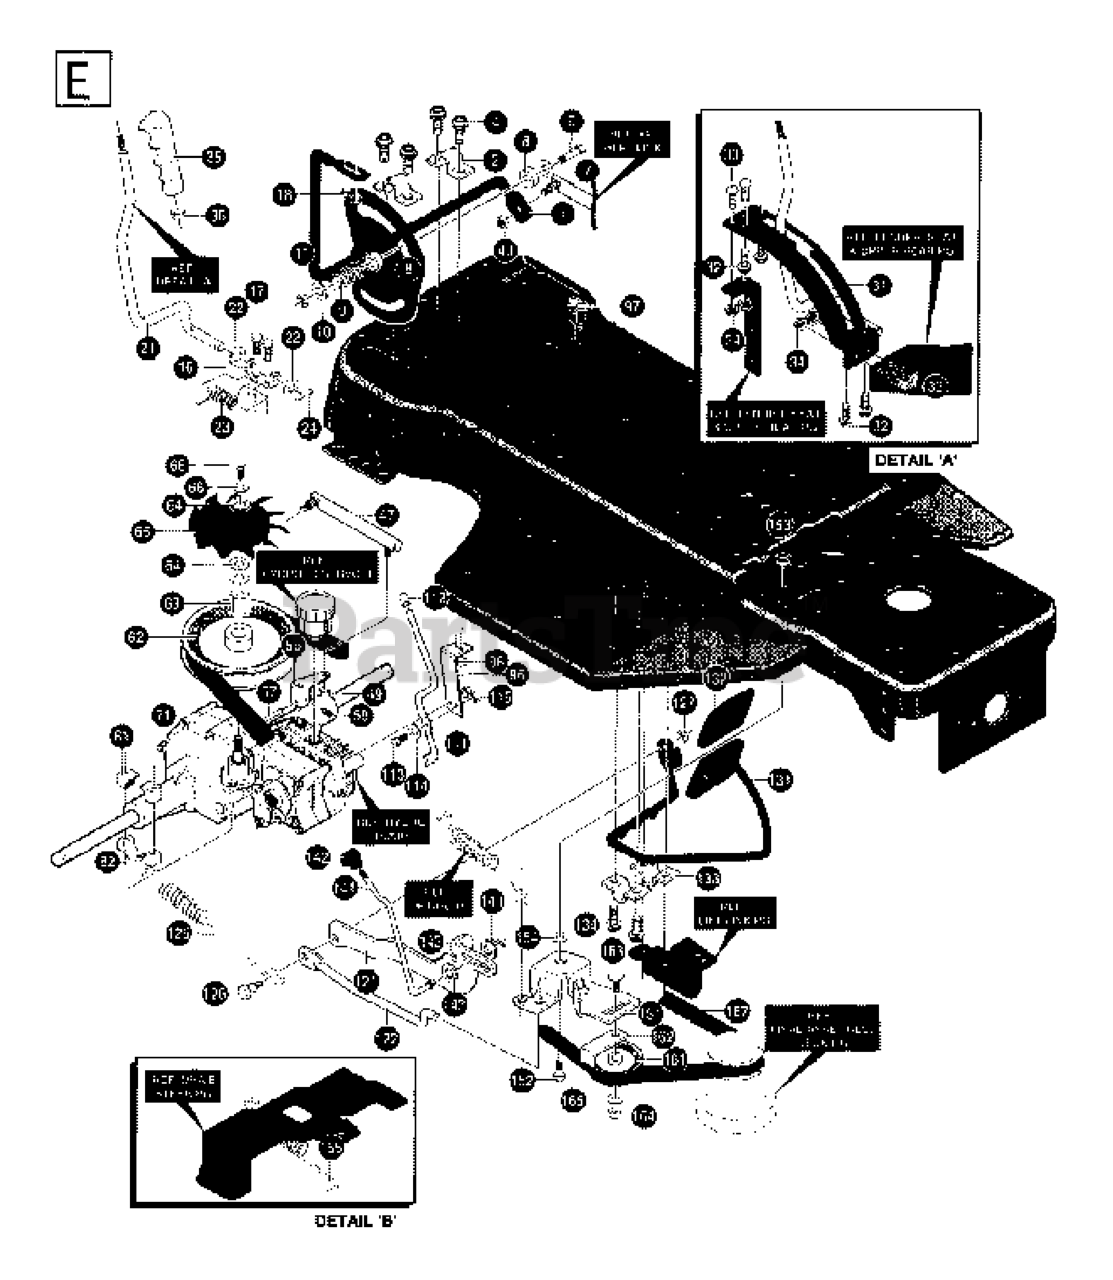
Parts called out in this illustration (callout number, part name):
2	SCREW
3	LOCK WASHER
4	NUT
11	WASHER
12	NUT
22	PIN
23	SCREW
29	WASHER
30	WASHER
33-1	LINK, L.H.
33-2	NUT
34-1	LINK, L.H.
34-2	NUT
35	SCREW
36	NUT
54	WASHER 3/8ä
55	NUT
62	SCREW
63	WASHER
64	NUT
72	SCREW
77	PIN
79	NUT
81	GEAR, STEERING
84	NUT
91	LINK
93	WASHER
94	NUT
97	SCREW
98	SCREW
99	NUT
100	WASHER
101	WHEEL CPL.
